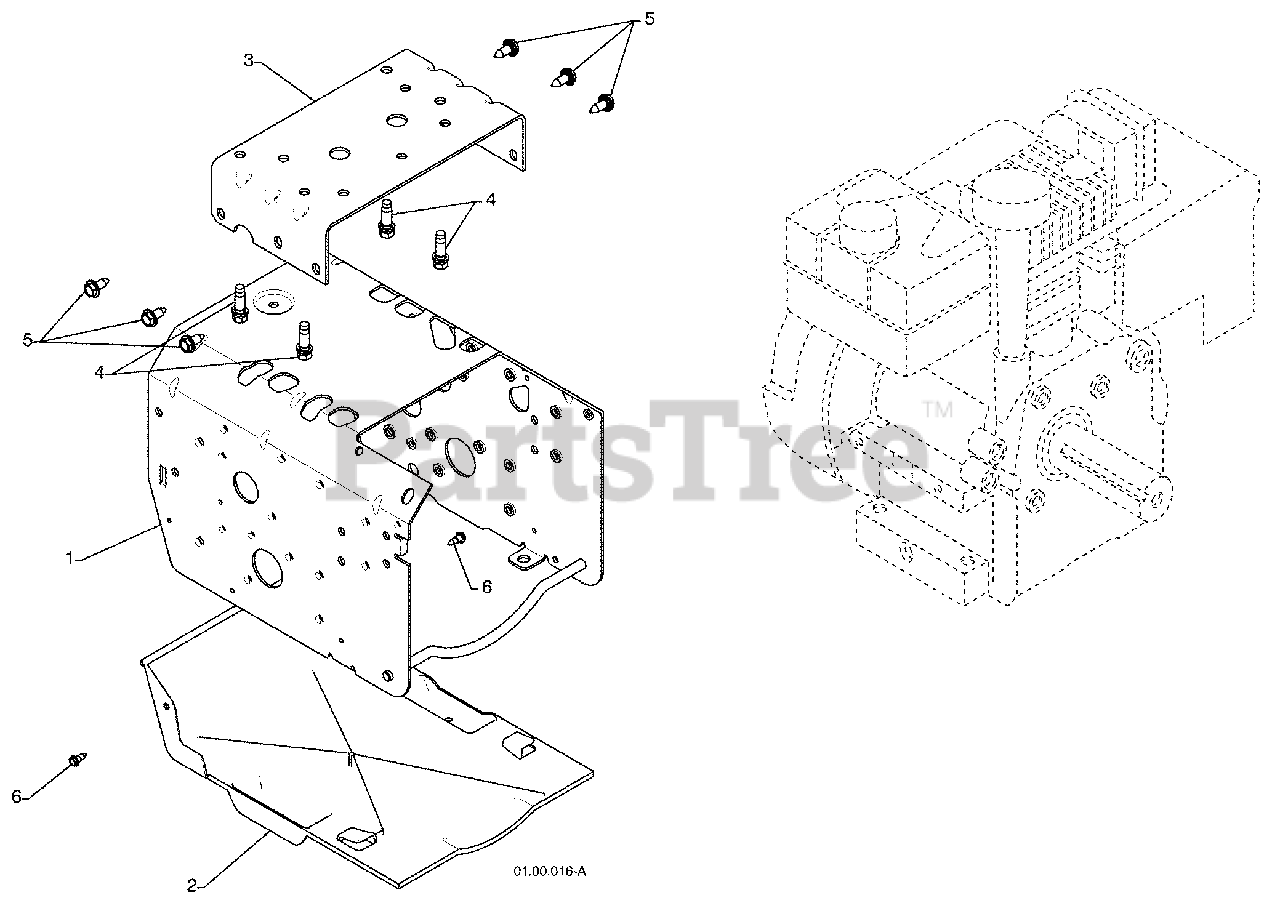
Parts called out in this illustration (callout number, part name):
2	BOTTOM PAN
3	ENGINE MOUNT PLATE
4	BOLT 3/8-16
5	SCREW 5/16-18 X .750
6	SCREW 10-24 X .625
